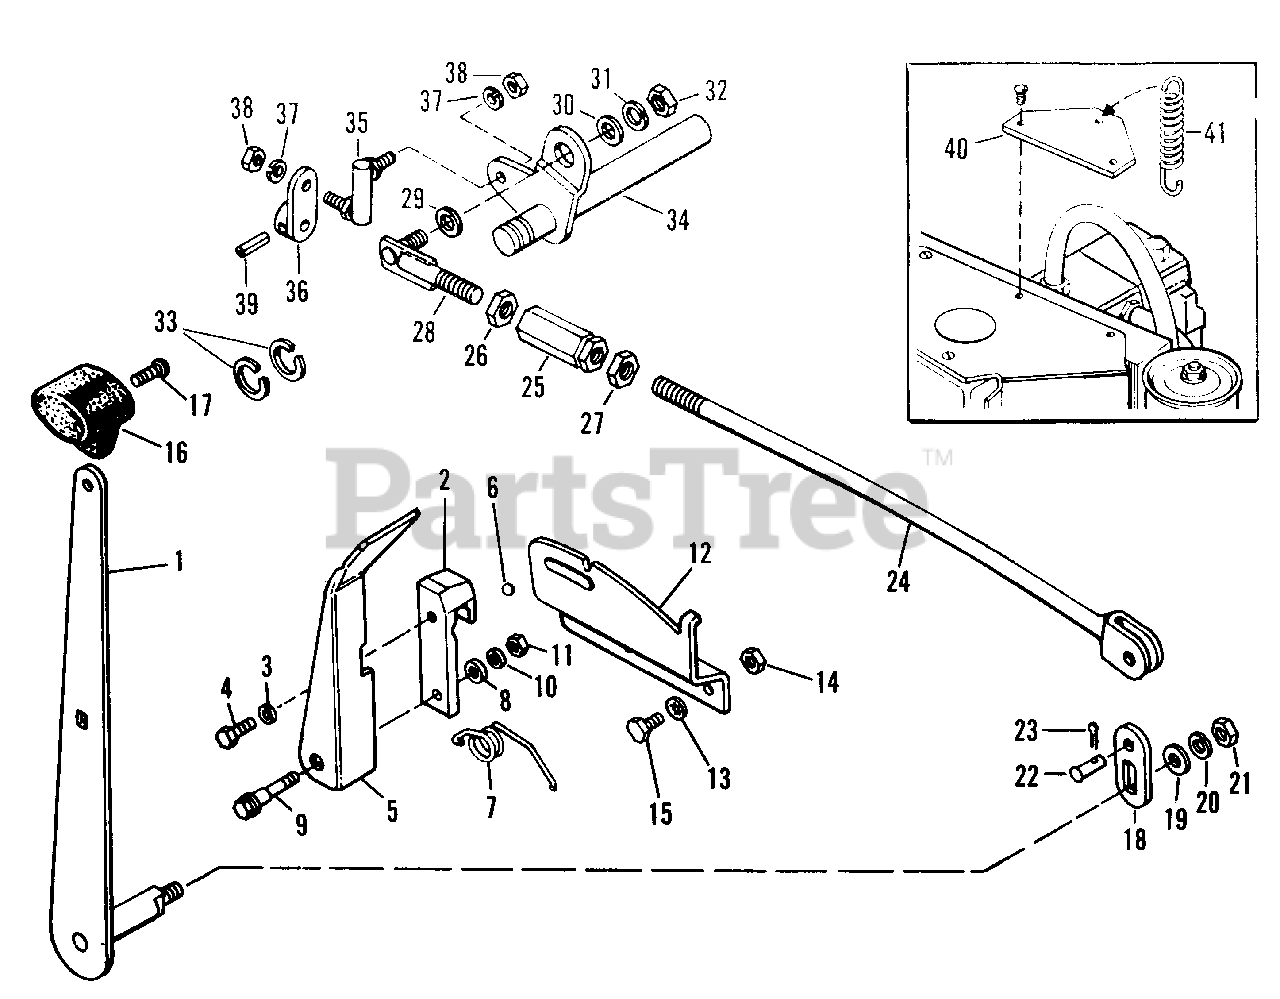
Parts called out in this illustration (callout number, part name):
1	Lever Assembly
2	Stop Clamp
3	Lock Washer, 1/4" Std.
4	Hex Capscrew, 1/4"-20 N.C. x 1/2"
6	Shift Ball Handle, 5/16"
9	Shoulder Bolt
10	Plain Washer, 1/4"
11	Full Hex Lock Nut, 1/4"-20
13	Shakeproof Lock Washer, 5/16"
14	Twin Pilot Nut
15	Special Screw
17	Screw, Thd. Form., 1/4"-20
19	Plain Washer, 3/8"
20	Lock Washer, 3/8"
21	Full Hex Nut, 3/8"-16
23	Cotter Pin, 3/32" x 3/4"
24	Rod Assy., Control, Front
25	Turn Buckle
26	Full Hex Nut, 7/16"-14 L.H.
27	Full Hex Nut, 7/16"-14 R.H.
28	Rod Assy., Rear Control
30	Plain Washer, 5/16"
31	Lock Washer, 5/16"
32	Full Hex Nut, 3/8"-16
33	Retaining Ring
34	Shaft Assy. Control
35	Ball Joint, Double End
36	Link Assy. Control
37	Lock Washer, 5/16"
38	Full Hex Nut, 5/16"-24
39	Roll Pin, 1/4" x 1-1/4"
40	Spring Clip
